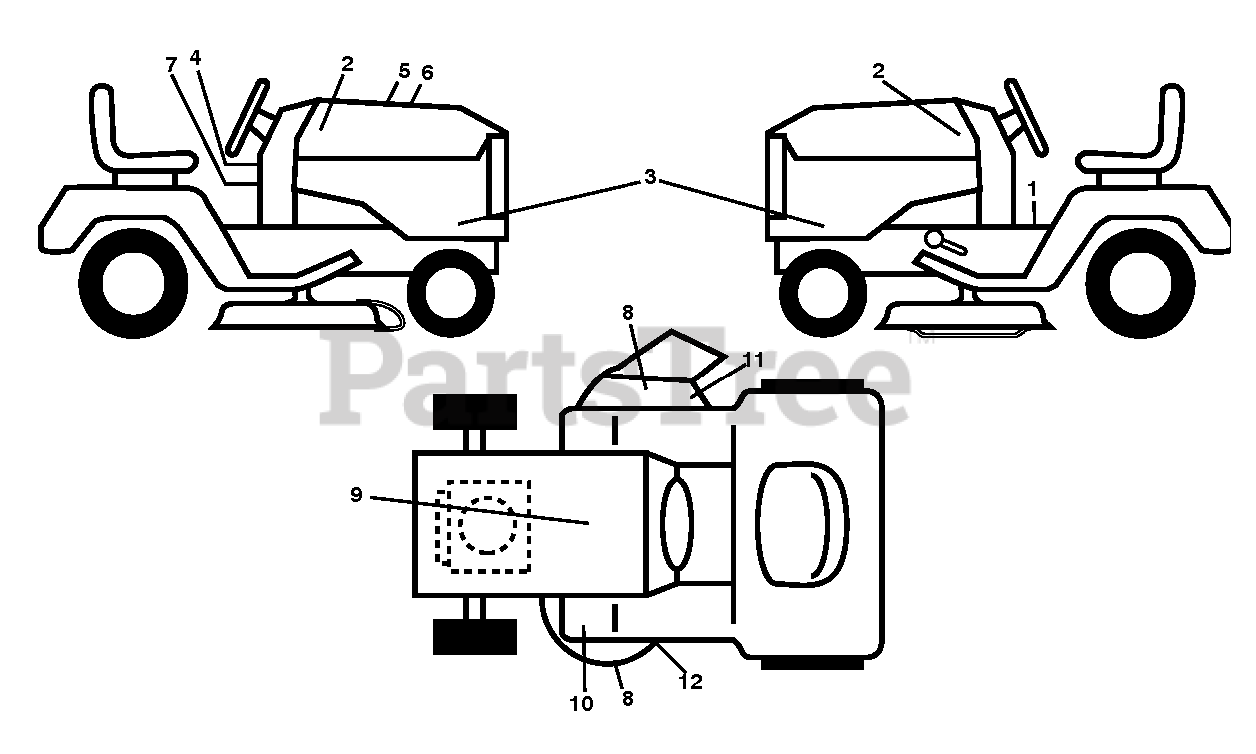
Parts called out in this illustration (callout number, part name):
1	DECAL.FENDER.WARNING
2	DECAL.BADGE.170MM.TEXTLOGO.
3	RP DECAL.SDPL.HUSQ.YTH24V42LS
4	DECAL, WARNING SPARK ARRESTOR
5	DECAL.WARNING.CUST.RESP.E85.
7	LABEL.EMISS.CA.HUSQ/LOWES.2011
8	DECAL, NO STEP
9	DECAL BTRY SYMBOLS
10	DECAL.PEDAL.HUSQ.CROWN
11	DECAL, CAUTION
12	DECAL.MOWER.SCH.48/54
